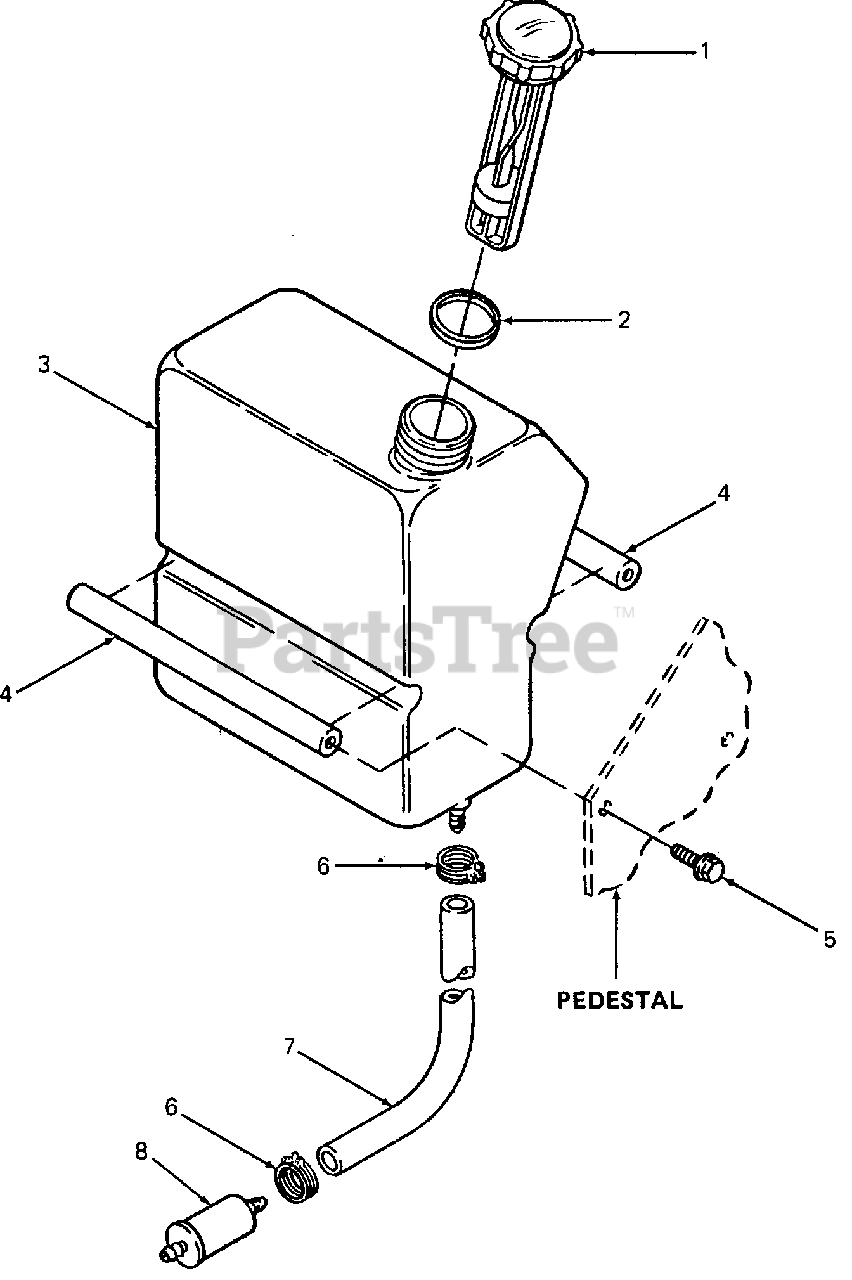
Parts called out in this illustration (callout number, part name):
1	Cap w/Gauge, Fuel
2	Gasket, Fuel Tank Cap
3	Tank, Fuel
4	Tube, 11.27 Lg
5	Screw, Hex Wash Hd B Tapp, 5/16-18 X .50 Lg
6	Clamp, Hose
7	Line, Fuel, 20 in. Lg
8	Filter, Fuel
